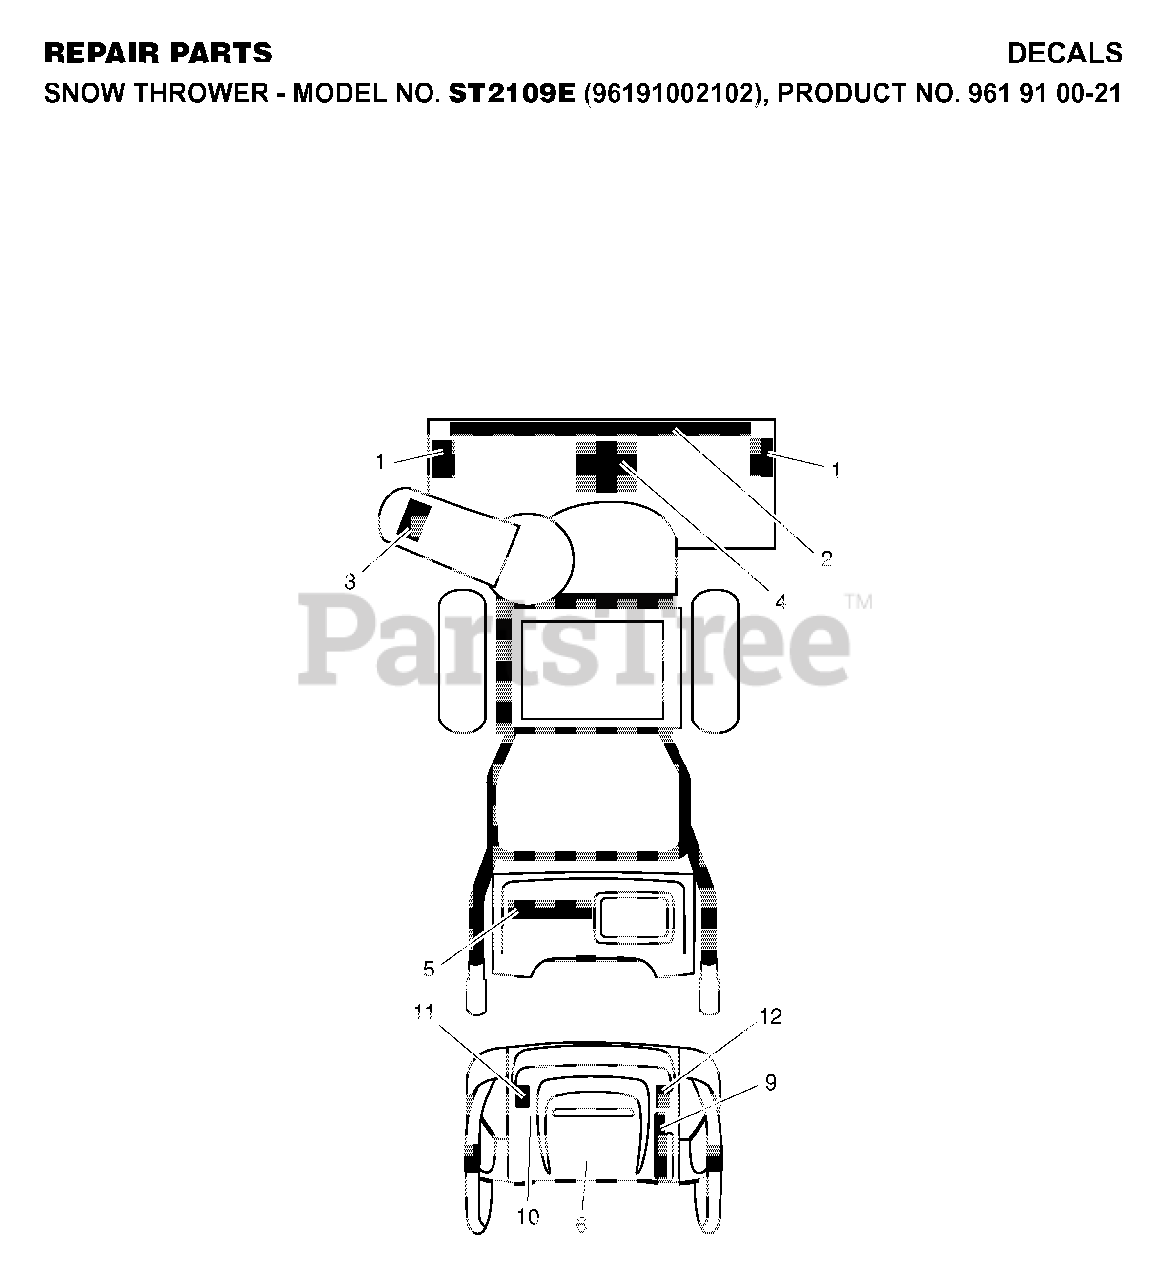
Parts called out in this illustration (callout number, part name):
1	DECAL.AUGER.SAFETY.
3	DECAL.CHUTE.SAFETY.
4	DECAL.AUGER."
6	DECAL.CONSOLE.INSTRUCTION
10	DECAL.REM.DEFLECTOR.LT
11	DECAL.POWER.STEER.LT.TRIG.INT
12	DECAL.POWER.STEER.RT.TRIG.INT
